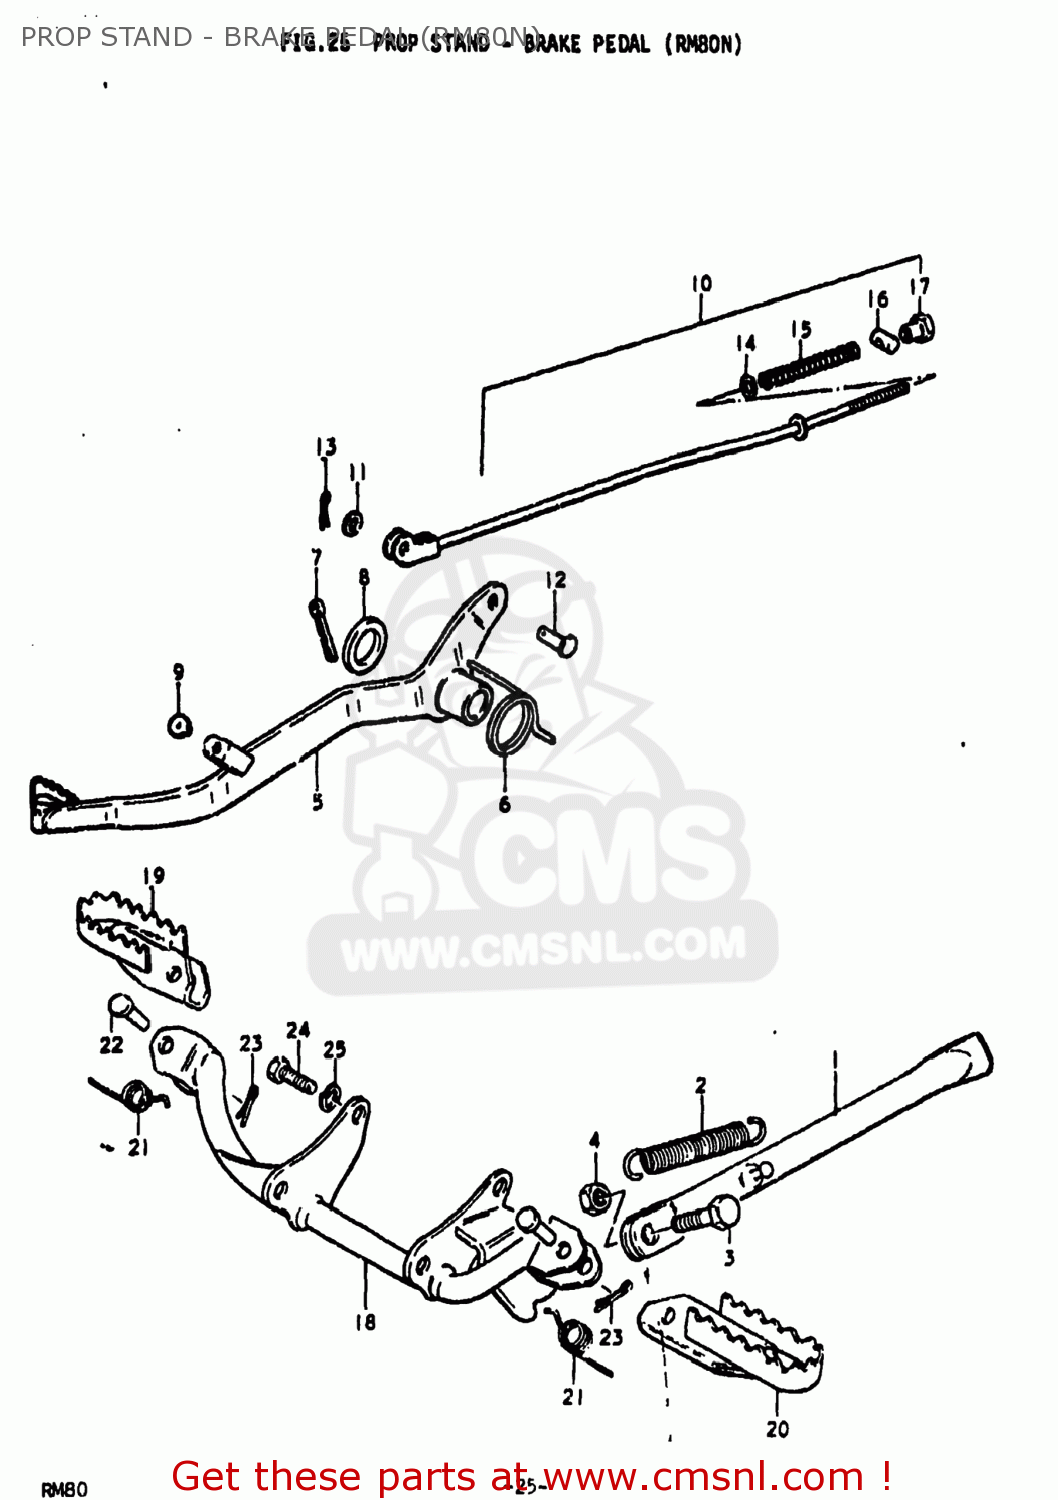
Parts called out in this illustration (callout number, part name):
1	STAND,SIDE
2	SPRING
3	BOLT
4	NUT
5	PEDAL,BRAKE
6	SPRING
7	COTTER PIN
8	WASHER(15.5X26X2.3)
9	STOPPER,BRAKE PEDAL
10	ROD ASSEMBLY,REAR BRAKE
11	WASHER
12	PIN(L:13.5)
13	PIN 20X20
14	WASHER
15	SPRING
16	PIN(11X18)
17	NUT
18	BAR,FRONT FOOTREST
19	FOOTREST,FRONT,RIGHT
20	FOOTREST
21	SPRING
22	PIN
23	PIN 20X20
24	BOLT
25	LOCK WASHER
